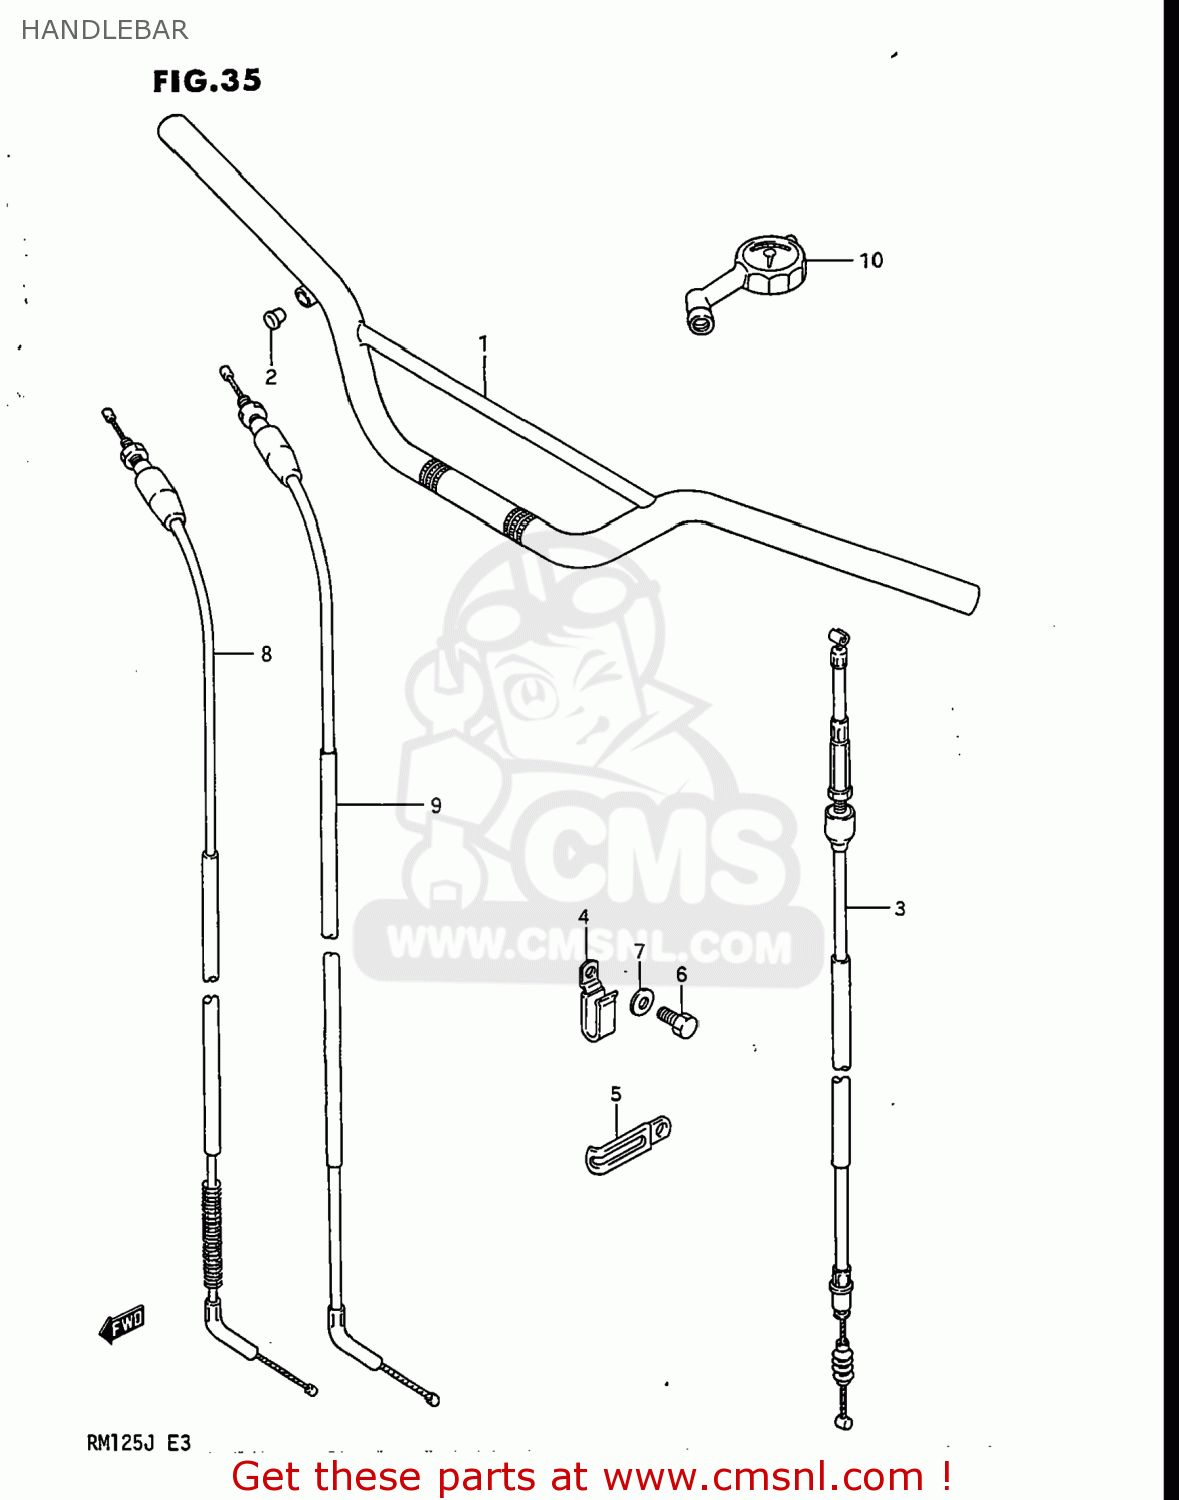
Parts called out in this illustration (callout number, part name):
1	HANDLEBAR
2	CAP(OD:14)
3	CABLE ASSEMBLY,CLUTCH
4	CLAMP
5	CLAMP
6	BOLT
7	WASHER
8	CABLE ASSEMBLY,THROTTLE
9	CABLE ASSEMBLY,THROTTLE
10	GAUGE ASSY,AIR PRESSURE
